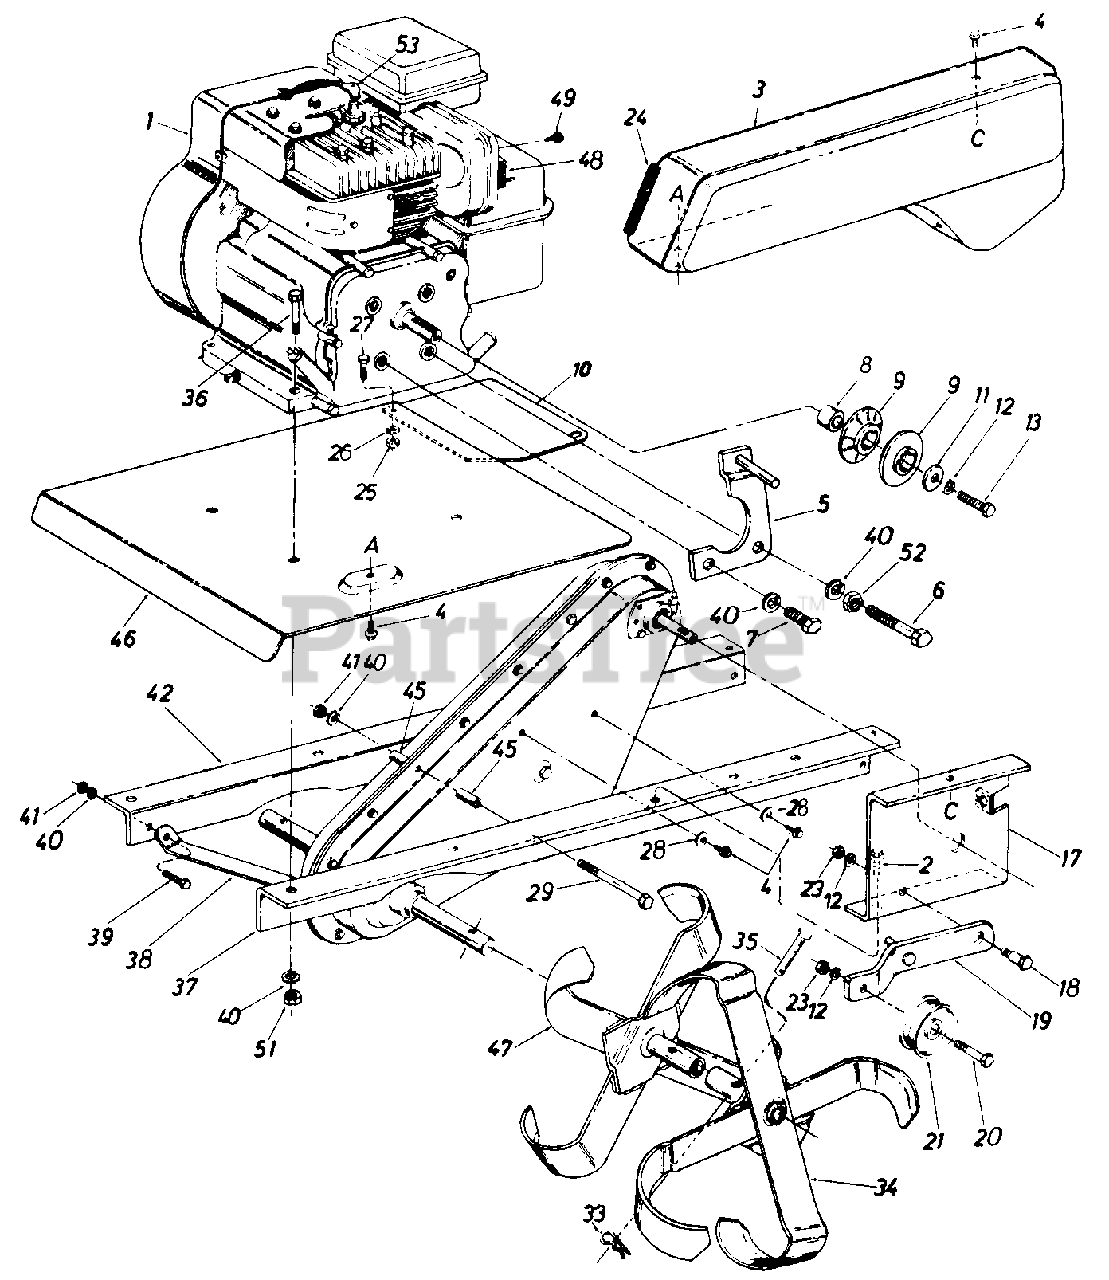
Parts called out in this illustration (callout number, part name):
1	Engine
2	Hex Self-Tap Scr. 5/16-24 x-.5"
3	Belt Cover
4	Hex Self-Tap Scr. 1/4-20 x .5"
5	Belt Keeper Brkt. Ass'y.
6	Hex Bolt 5/16-24 x 2.25" Lg. (Gr. 5)
7	Hex Bolt 5/16-24 x .62" Lg. (Gr. 5)
10	Tine Shield Extension
11	Fl-Wash. 3/8" I.D. x 1.25"
12	L-Wash. 3/8" I.D.*
13	Hex Bolt 3/8-24 x 1.00" Lg.
17	Idler Mounting Brkt.
18	Shld. Bolt
19	Idler Bracket Ass'y.
20	Hex Bolt 3/8-16 x 1.5" Lg.
21	Idler Pulley
23	Hex Jam Nut 3/8-16 Thd.
24	Trim Strip-3"
25	Hex Nut 1/4-20 Thd.*
26	L-Wash. 1/4" I.D.*
27	Hex Bolt 1/4-20 x .62 Lg.*
28	Bell-Wash. .26 I.D. x .75 O.D.
29	Hex Bolt 5/16-18 x 3" Lg.*
33	Hairpin Cotter
36	Hex Bolt 5/16-18 x 1.5" Lg.
37	Frame Rail-L.H.
38	Front Brace Brkt.
39	Hex Bolt 5/16-18 x .75" Lg.'
40	L-Wash. 5/16" I.D.*
41	Hex Cent. L-Nut 5/16-18 Thd.
42	Frame Rail-R.H.
49	Hex Self-Tap Scr. #8-32 0 x.38" Lg.
51	Hex Nut 5/16-18 Thd.*
52	Hex Nut 5/16-24 Thd.*
53	Spark Plug Boot
